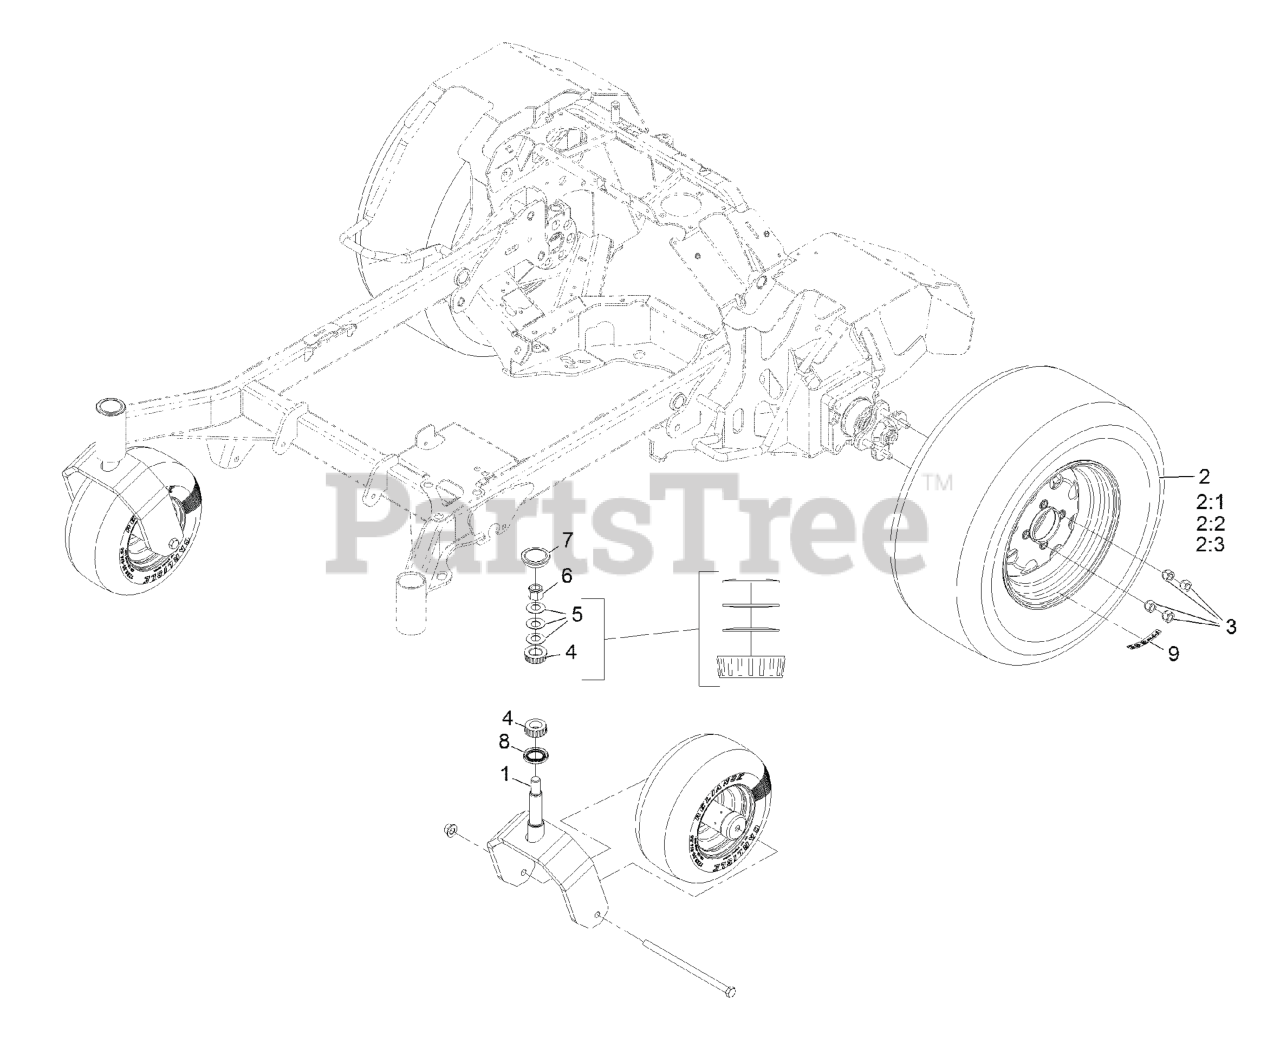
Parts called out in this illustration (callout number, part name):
2	ASM, WHEEL AND TIRE
2:1	TIRE, 23 X 9.50-12
2:2	RIM, 12 X 7
2:3	Stem-Valve
3	NUT-LUG
4	Cone-Bearing Tapered Roller
5	WASHER-BELLVILLE
6	NUT-LOCK, NI
7	CAP-GREASE
8	SEAL-GREASE
9	DECAL-TORQUE, WHEEL HUB LUG
